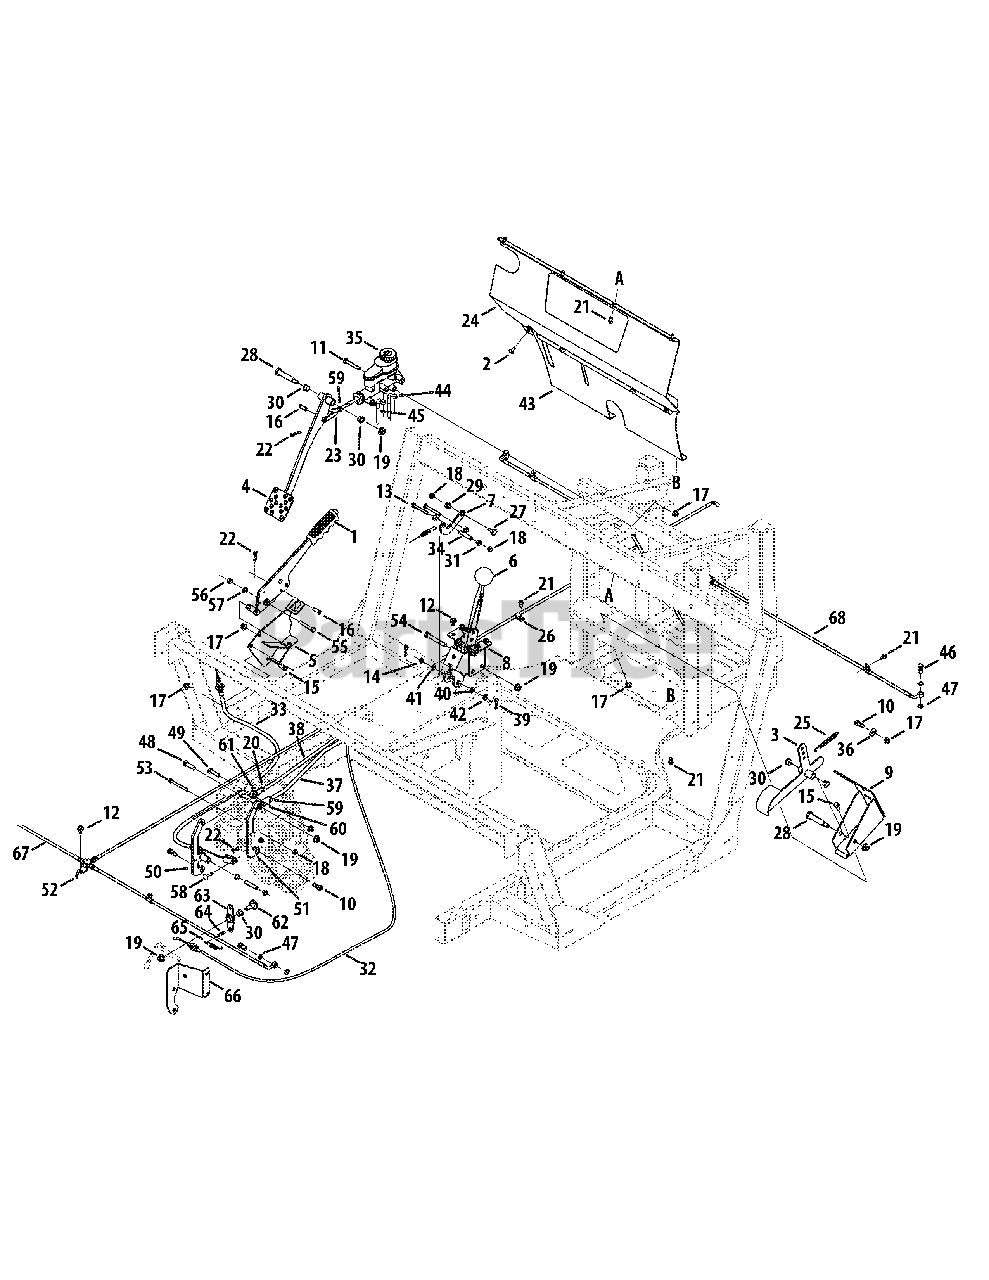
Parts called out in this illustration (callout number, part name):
1	Lever Assembly, Brake
2	Screw, ab, 1/4-14, 0.625,
3	Pedal Assembly, Accelerator
4	Pedal Assembly, Brake
5	Bracket Assembly, Park Brake
6	Shaft Assembly, Hurst, 4x4
6	Shaft Assembly, Hurst, 4x2
7	Plate, Pawl, Over Center
8	Shaft, Console Mount
9	Bracket, Accelerator Pedal
10	Screw, Shldr, .372 x .375, 5/16-18
11	Screw, 5/16-18, 2.00, Gr5, Patch
12	Screw, Tt, 5/16-18, 0.500
13	Screw, 1/4-20, 2.25, Gr5, Std
14	Bearing., Flange, .315 ID
15	Screw, 5/16-18, .75, Gr5, Std
16	Pin, Clevis, 312 Od x 1.0"
17	Nut, Flange Lock, 5/16-18
18	Nut, Flange Lock, 1/4-20, Nylon
19	Nut, Flange Lock, 3/8-16, Nylon
20	Nut, Jam, 5/16-24, Gr5
21	Screw, Tt, 1/4-20 x .500
22	Pin, Cot, 3/32, 1.0
23	Yoke, 5/16-24
24	Panel, Dash, Upper
25	Spring, External, .38 Od x 3.6
26	Clamp, Hose
27	Screw, Shldr, .375x.380, 1/4-20
28	Screw, Shldr, .500 x 2.230, 3/8-16
29	Plastic Bushing .380 Id
30	Bearing, Flange, Nyliner, .500 x .34
31	Bearing, Flange, .375 x .580 x .250
32	Cable, Cont, Diff, Lock
33	Cable, Cont, Park, Brake, 4x4
34	Spacer, Pivot, Diff Lock
35	Cylinder, Master, Tandem
36	Washer, Flat, .349 x .879 x .063
37	Link, Shaft, F N R
38	Link, Shaft, Hi Lo, 4x4
39	Pin, Cotter, 1/16 x .75
39	Pin, Cotter, .072 Dia. x 1.13 Lg.
40	Washer, Flat, .385 x .62 x .063
41	Washer, Flat, .330 x .630 x .0635
42	Bearing, Flange, .377 Id
43	Panel, Dash, Lower, 4x4
44	Hose, Brake, Master Cyl, Front
45	Hose, Brake, Master Cyl, Rear
46	Fitting, Banjo Ftg Bolt, M10 x 1.00
47	Fitting, Banjo Ftg Crush Washer
48	Screw, 3/8-16 x 1.25
49	Screw, 5/16-18 x 1.25
50	Lever, Assembly, Shift, Hi-Lo, 4x4
51	Lever, Assembly, Shift, F N R
52	Fitting, Tee, -3, 45 Deg Flare
53	Screw, 1/4-20 x 2.50
54	Screw, 3/8-16 x 2.75
55	Screw, 5/16-18 x 2.00
56	Nut, Jam, 5/16-18
57	Washer, Flat, .344 x .688 x .065
58	Pin, Clevis
59	Nut, Jam, 3/8-24
60	Rod, End, 3/8 ID
61	Rod, End, 5/16 ID
62	Screw, shldr, .500 dia x .434
63	Lever, Assembly, Diff Lock
65	Spring, external, .38od x 2.10
66	Bracket, diff, Cable,mnt
67	Hose, brake, rear
68	Hose, brake, front
